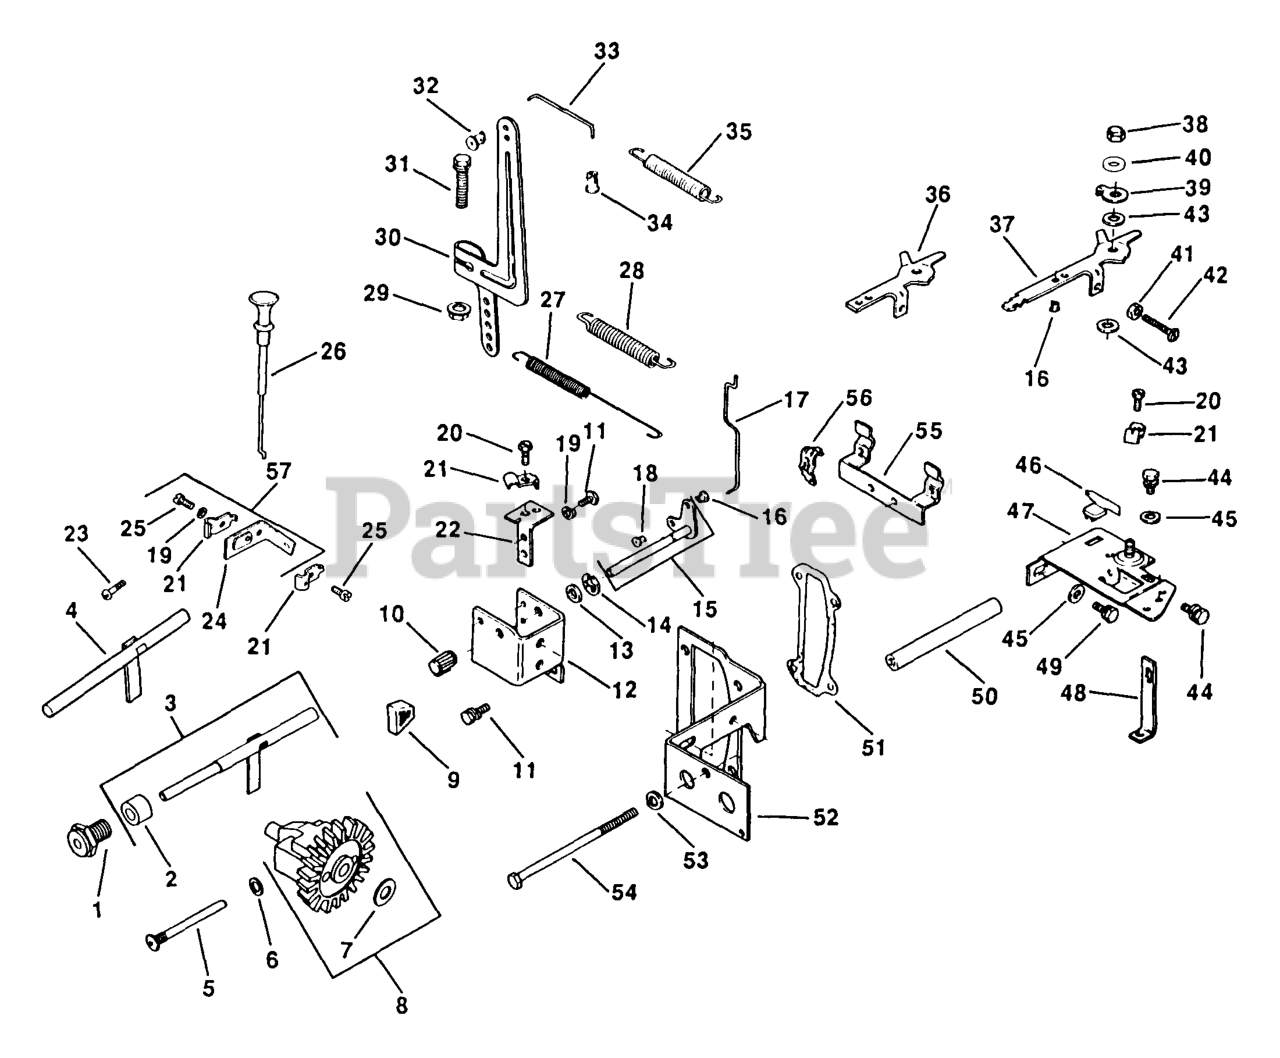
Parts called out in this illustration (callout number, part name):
1	BUSHING
2	SPACER USE 25 112 17-S
3	KIT, SHAFT
4	KIT - USE A-235256-S
8	KIT, GOVERNOR GEAR
10	KNOB
10	KNOB - DISCONTINUED
11	SCREW DISCONTINUED
12	BRACKET - DISCONTINUED
13	BUSHING - DISCONTINUED
15	KIT, LEVER - DISCONTINUED
17	LINKAGE, CHOKE - DISCONTINUED
18	BUSHING - USE 25 158 09
29	PALNUT, 1/4-20
34	BUSHING - USE 25 158 11
36	LEVER-DISCONTINUED
38	NUT USE 25 100 13-S
39	TAB - USE 52 448 02
40	WASHER, FLAT 1/4" (O.D. 5/8")
41	NUT, MACH SCREW #10-24 GRD 2 USE 25 100 17-S
42	SCREW, SLT PAN HD 10-24X1" USE 25 086 65-S
43	WASHER, SPRING 1/4"
45	WASHER, FLAT 1/4" (O.D. 1/2")
47	BRACKET - DISCONTINUED
48	BRACKET - DISCONTINUED
49	SCREW, SEMS 1/4-20X5/8" USE 25 086 539-S
50	SPACER - DISCONTINUED
51	GASKET, CAMSHAFT COVER
52	BRACKET - DISCONTINUED
53	WASHER, SPRING LOCK 1/4"
54	SCREW - DISCONTINUED
55	BRACKET - DISCONTINUED
